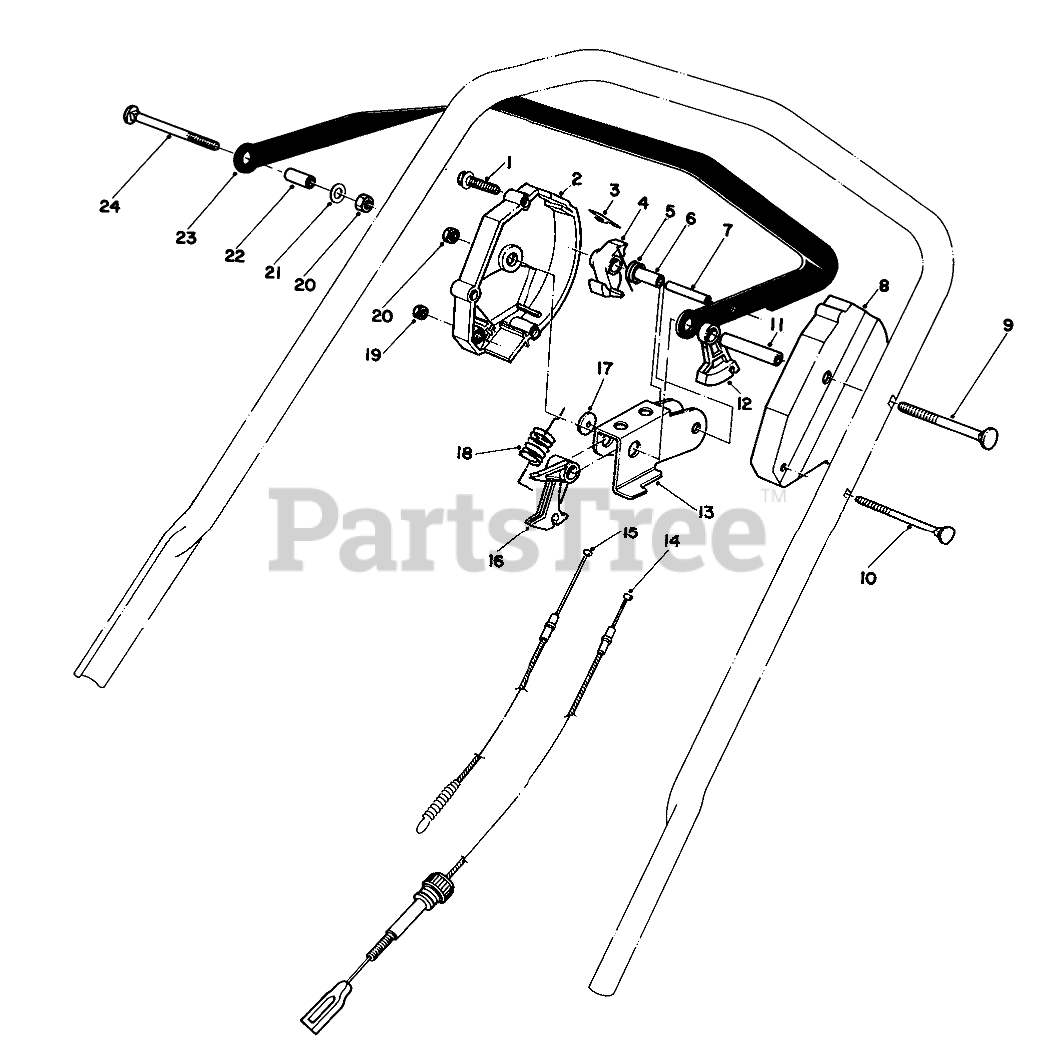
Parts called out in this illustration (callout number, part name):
1	SCREW-HWHTF
2	Housing Control R.H.
3	LEAF SPRING
4	HOOK-CONTROL
5	SPRING-TORSION
6	SPACER
7	PIN-ROLL, SLOTTED
8	HOUSING-CONTROL, LH
9	5/16-18 X 3 HNDLE SCREW
10	HANDLE SCREW
11	TUBING-SPACER
12	LEVER-TRACTION
13	Rocker
14	TRACTION CABLE
15	Cable-Clutch
16	LEVER-CABLE
17	PLASTIC WASHER
18	Spring-Extension
19	NUT-LOCK, NI
20	NUT-LOCK, NI
21	WASHER-PLAIN
22	Spacer
23	Bar-Control
24	5/16-18 X 2 HNDLE SCREW
